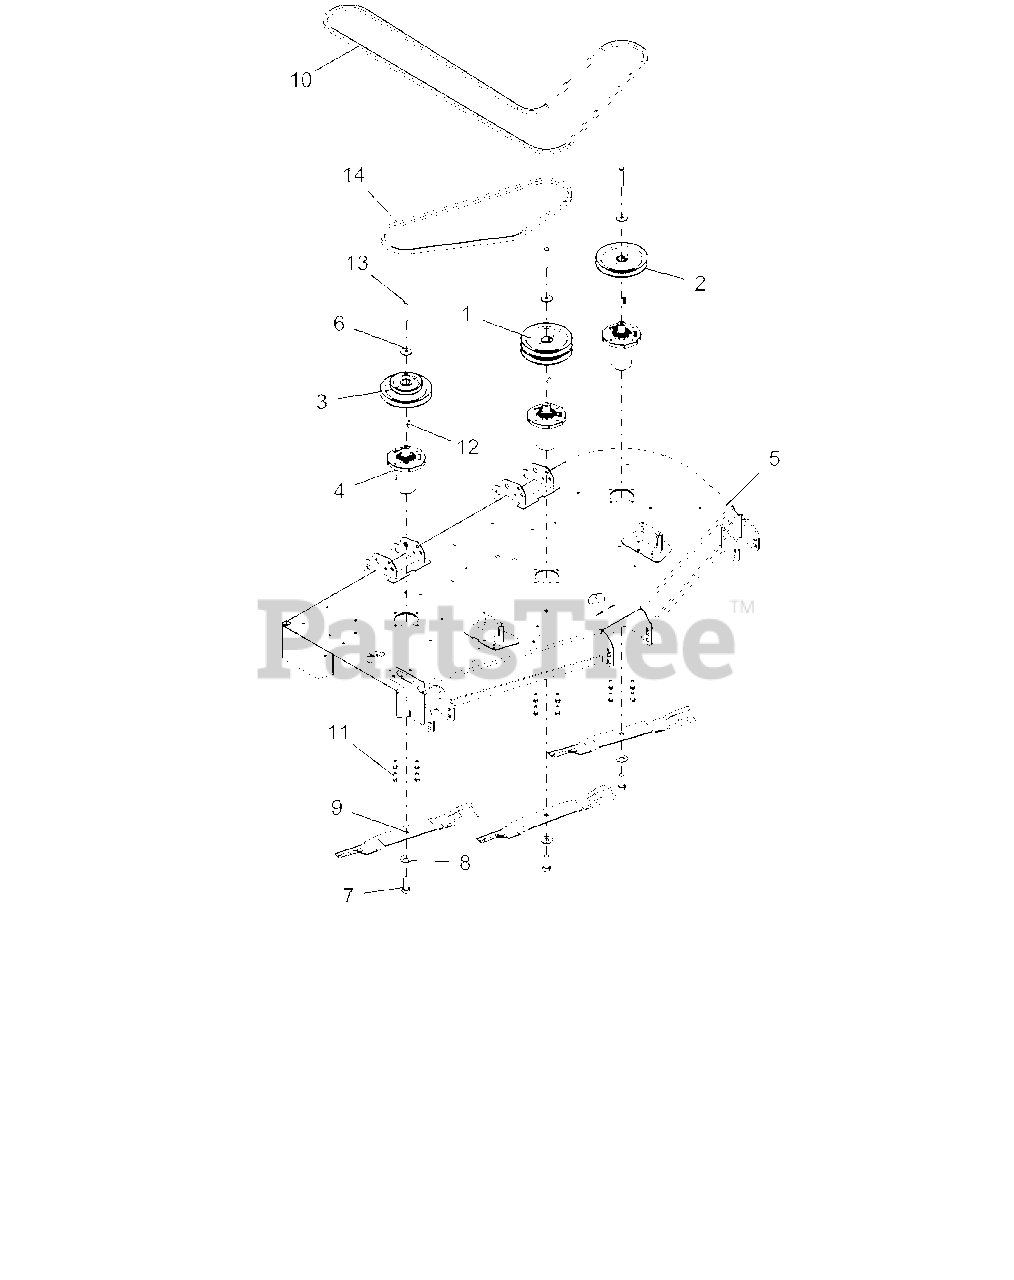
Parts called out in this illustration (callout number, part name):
1	PULLEY, DOUBLE-1"ID X 6.75"OD
2	PULLEY, V-1" ID X 6.75" OD
3	PULLEY, DBL-1"IDX6.75"&4.25"OD
4	ASM, MAINT FREE SPINDLE
5	KIT,DECK - 60" W/SAFETY DECALS
6	RETAINER, SHEAVE
7	BLT-HEX .62-18X1.75 GR8 YWZC
8	WSHR-BLVL .669X1.535X.138
9	BLADE, 20.5"
10	HEX BELT, BB-WRAPPED
11	BLT-HEX .38-16X1.0 GR8 YZ EP30
12	KEY, SQ .25X.25X1.00 RC 40-50
13	BLT-HEX .38-16X2.75 GR8 YWZC
14	V-BELT, B-COGGED
